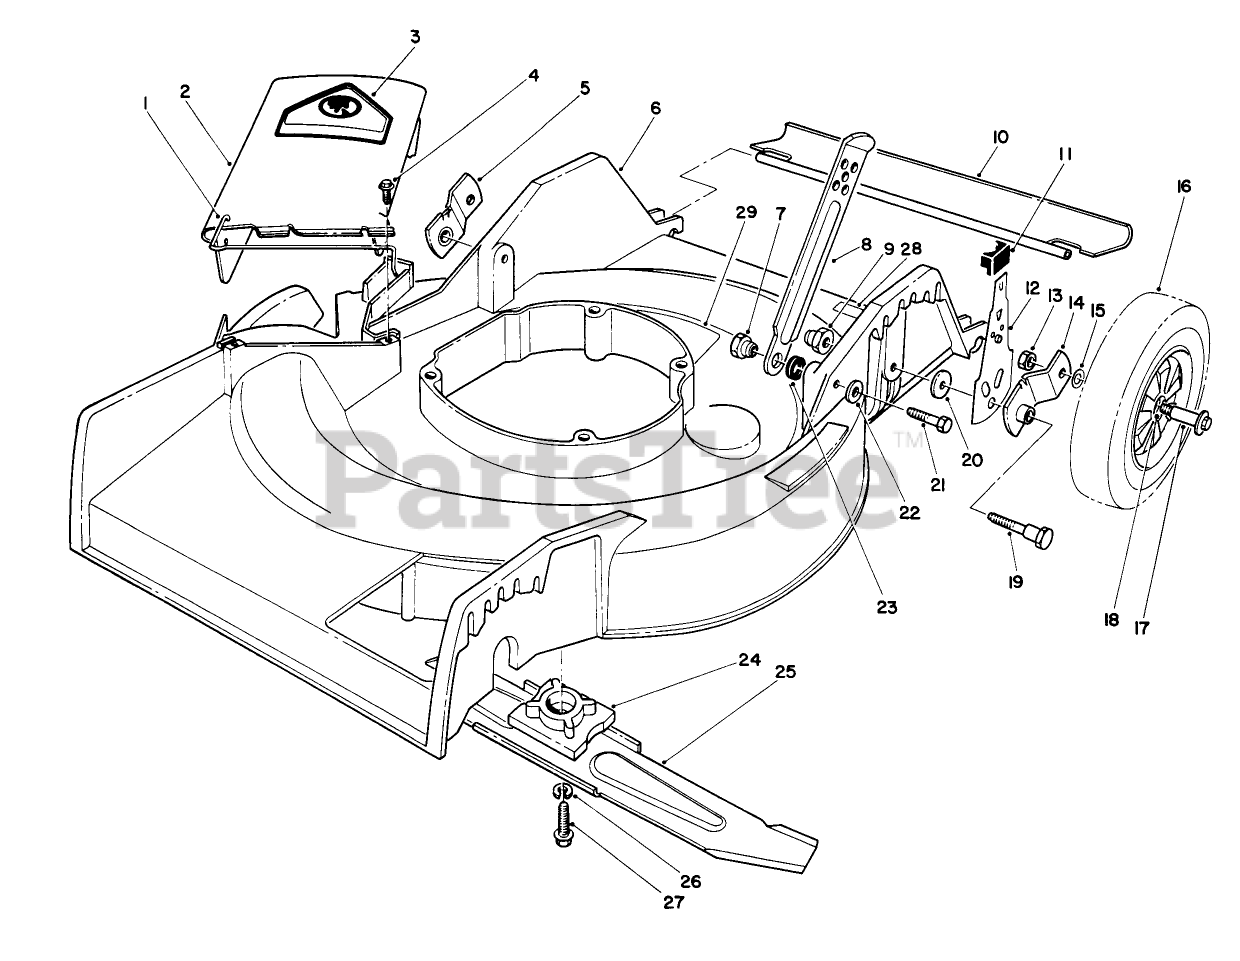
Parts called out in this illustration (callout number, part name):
3	DECAL-DANGER
4	SCREW-HWH
7	HANDLE PIVOT NUT
9	HANDLE PIVOT NUT
11	KNOB-ARM
12	REAR SPRING ARM ASM
13	NUT-LOCK
15	WASHER
16	WHEEL TIRE ASM 8 IN
17	WHEEL BOLT
18	BUSHING
19	5/16-18 PIVOT SCREW
20	PIVOT WASHER
21	SCREW-HH
22	WASHER-LOCK
23	SPACER
24	BLADE RETAINER
26	WASHER-LOCK
27	SCREW-HH
28	DECAL-WARNING
29	DECAL-INSTRUCTION, SAFETY
